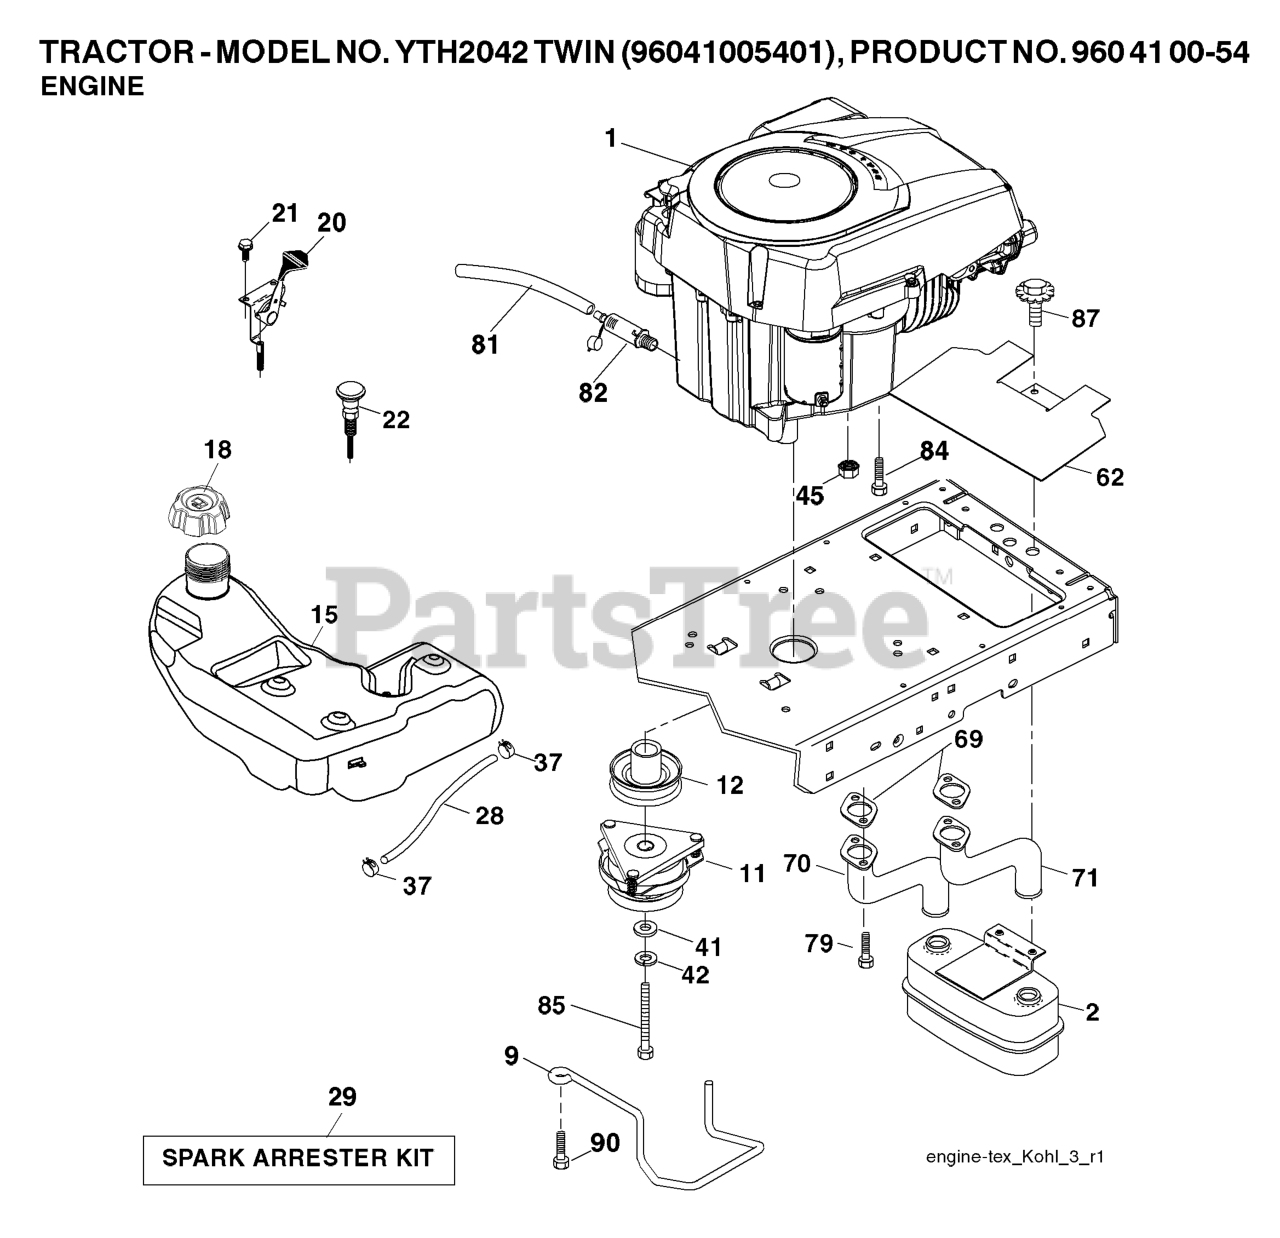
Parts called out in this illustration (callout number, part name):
2	MUFFLER.TWIN.CYL.LOW.TONE
9	KEEPER.BELT.ENGINE.4.2
11	RB.CLUTCH.OGURA.4.4.PD
12	PULLEY.ENGINE.TUFFTORQ
15	TANK.FUEL.4GAL
18	CAP.FUEL.TANK.3"GREY
20	THROTTLE CONTROL
21	SCREW.#10 X 0.750.BOS
22	CONTROL.CHOKE.ERGO.PUSH-IN.BLA
28	REPL BY 532 00 85-43
29	KIT.SPARK ARRESTOR 794945 B&S
37	HOSE CLAMP
42	LOCKWASHER
45	NUT
62	RP SHIELD HEAT MUFFLER
69	GASKET.EXHAUST.KOHL.CV18-CV26
70	RP.PIPE-EXHAUST LH
71	RP.PIPE-EXHAUST RH
79	SCREW.SOCKET HD.5/16-1
81	TUBE, DRAIN OIL ASM.
82	PLUG DRAIN OIL EASY
84	SCREW 3/8-16X1
85	BOLT HEX 7/16-20X4-1/4"
87	BOLT.5/16-18UNCX3/4 W/SEMS.BLK
90	SCREW 3/8-16X1
